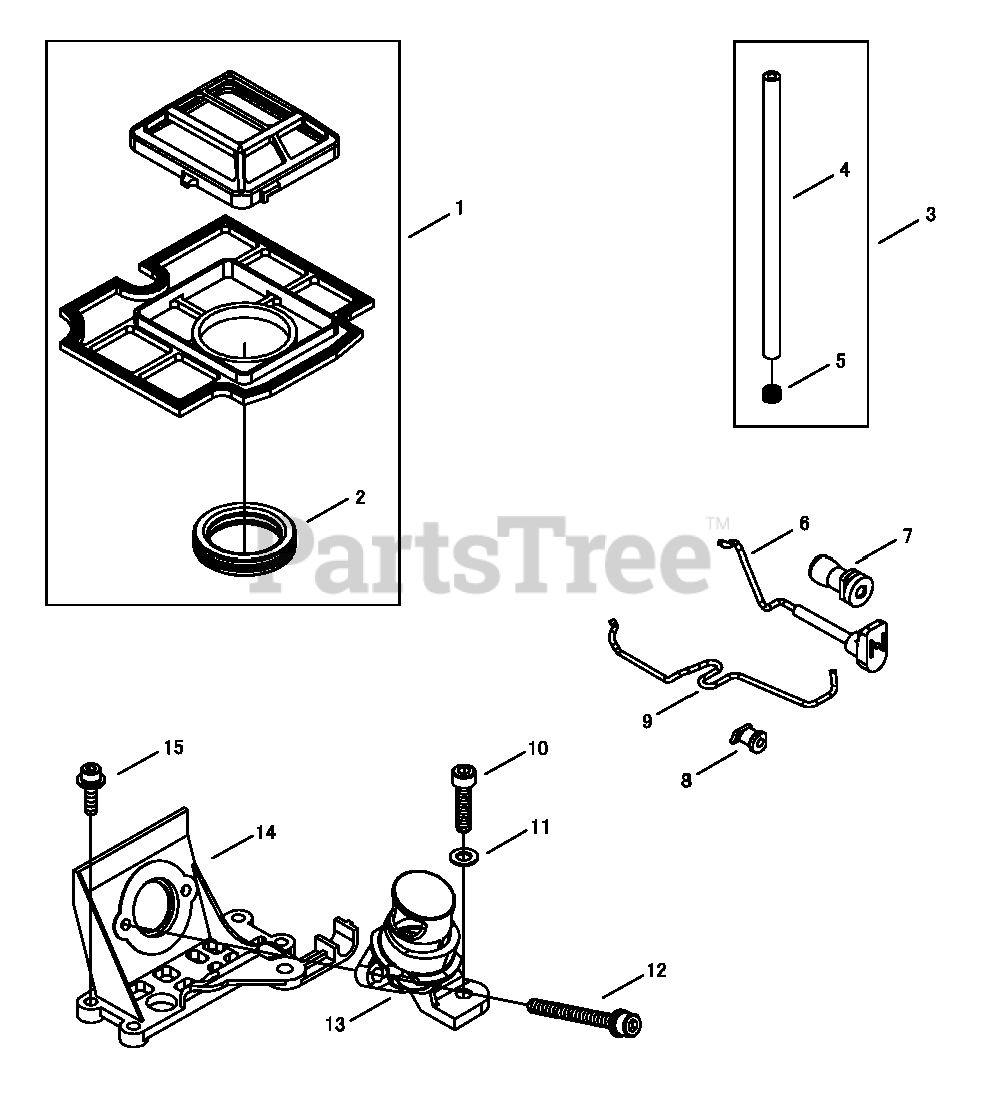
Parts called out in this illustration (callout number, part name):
1	FILTER, AIR
2	GROMMET
3	PIPE, PULSE
4	PIPE, PULSE
5	CLIP
6	ROD, CHOKE
7	GROMMET, CHOKE
8	GROMMET
9	ROD, THROTTLE
10	BOLT M5×18
11	WASHER 5.5×12×0.8
12	BOLT M5×50
13	ELBOW
14	INSULATOR, INTAKE
15	BOLT M4×16
